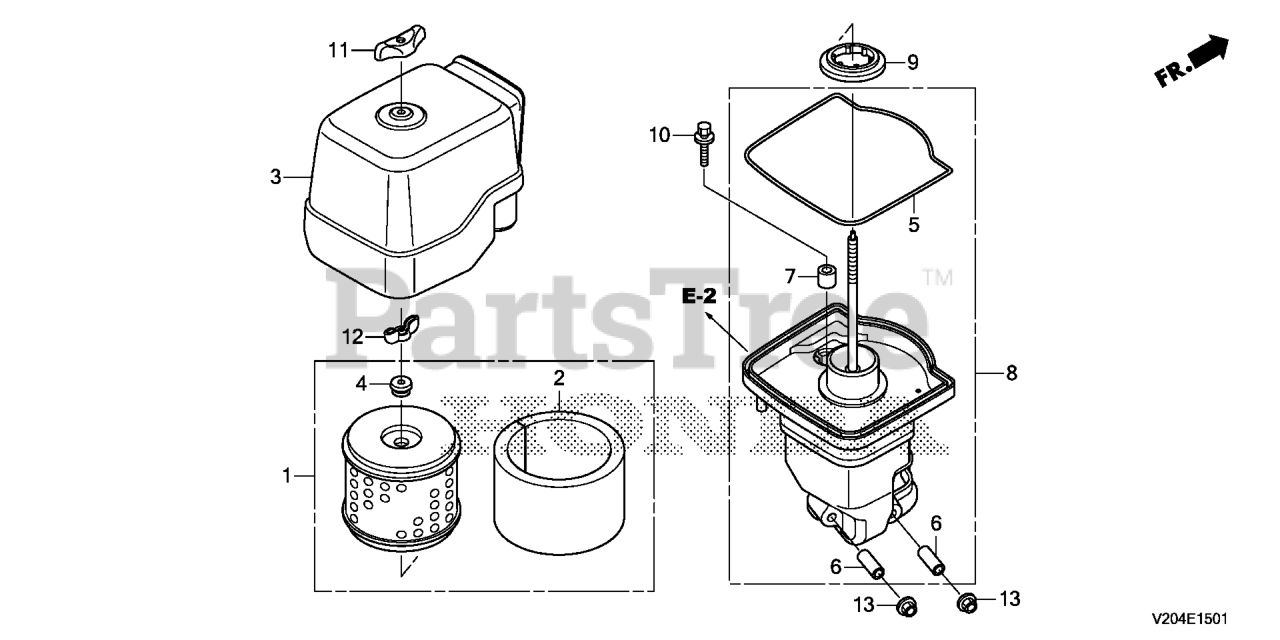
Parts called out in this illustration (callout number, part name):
1	ELEMENT, AIR CLEANER
2	FILTER (OUTER)
3	COVER ASSY., AIR CLEANER (CYCLONE)
4	GROMMET, AIR CLEANER
5	SEAL, AIR CLEANER COVER
6	COLLAR, AIR CLEANER
7	COLLAR B, AIR CLEANER
8	ELBOW, AIR CLEANER
9	GASKET, AIR CLEANER HOUSING
10	BOLT-WASHER (6X22)
11	NUT, AIR CLEANER
12	WINGNUT, TOOL BOX SETTING
13	NUT, FLANGE (6MM)
